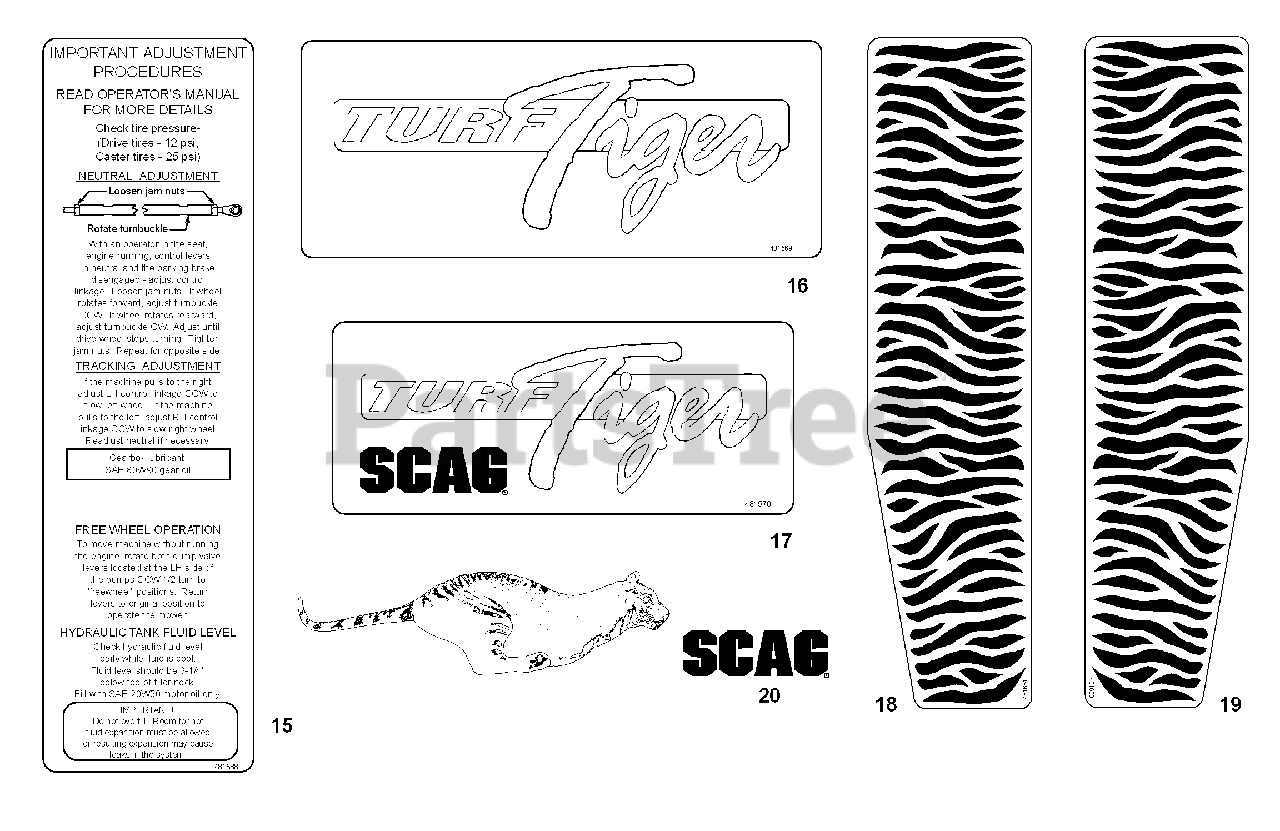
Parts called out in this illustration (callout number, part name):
15	Decal, Seat Support
16	Decal, Turf Tiger
17	Decal, Turf Tiger
18	Decal, Stripes-RH
19	Decal, Stripes-LH
20	Decal, Tiger
